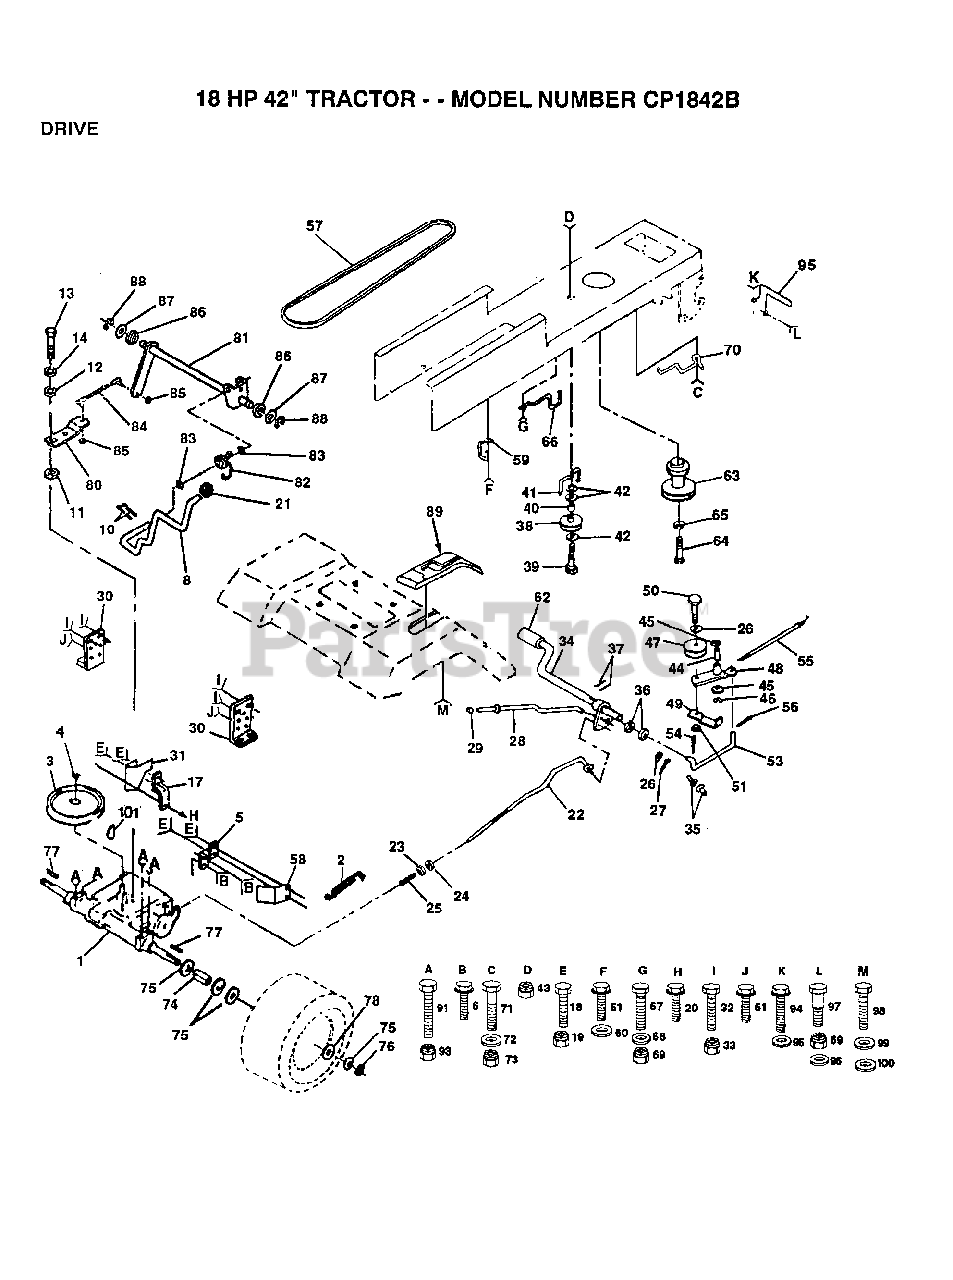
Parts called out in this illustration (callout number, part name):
3	"PULLEY,TRANSAXLE"
5	STRAP TORQUE
6	SCREW
8	"ROD,SHIFTER "
10	PIN COTTER 1/8
11	WASH-SHFT PLT LT
12	WASHER
14	LOCKWASHER
17	STRAP TORQUE
20	SCREW
21	KNOB T (1/2-HOLE)
22	BRAKE ROD
23	NUT
24	NUT
25	SPRING ROD LT
26	WASHER
27	COTTER PIN
28	BRAKE PARK ROD
29	PLUNGER CAP T
30	TRANSAXLE MTG BKT
31	"KEEPER,BELT LH"
32	BOLT
35	NYLON BEARING
36	WASHER LT
38	PULLEY.IDLER.FLAT
39	BOLT
40	SPACER T
41	BELT KEEPER LT
42	WASHER
44	"LY, BEARING"
45	WASHER LT
46	KLIP RING
48	ARM IDLER
49	RETAIN BELT
53	"LINK, CLUTCH T"
54	COTTER PIN
55	"SPRING, RETURN LT"
56	COTTER PIN
57	BELT-V
58	"KEEPER,BELT RH"
60	WASHER
61	SCREW
62	PEDAL COVER T
64	BOLT
65	LOCKWASHER
66	KEEPER.BELT.ENG.L
67	BOLT
68	WASHER
70	KEEPER BELT ENG
71	BOLT
72	WASHER
74	SPACER LT
75	WASHER
76	E-RING LT
77	SQUARE KEY
78	WASHER
80	ARM SHIFT TRANS
82	"SPRING,TORSION"
83	WASHER
84	TIE ROD
85	NUT 1/4-28
86	"BUSH,PIVOT T"
87	"WSHER,SHIM"
88	RING T
91	BOLT
94	SCREW GTV
95	MUFFLER GUARD
96	WASHER HYT
97	BOLT D
98	SCREW
99	"WASHER,LOCK"
100	WASHER
